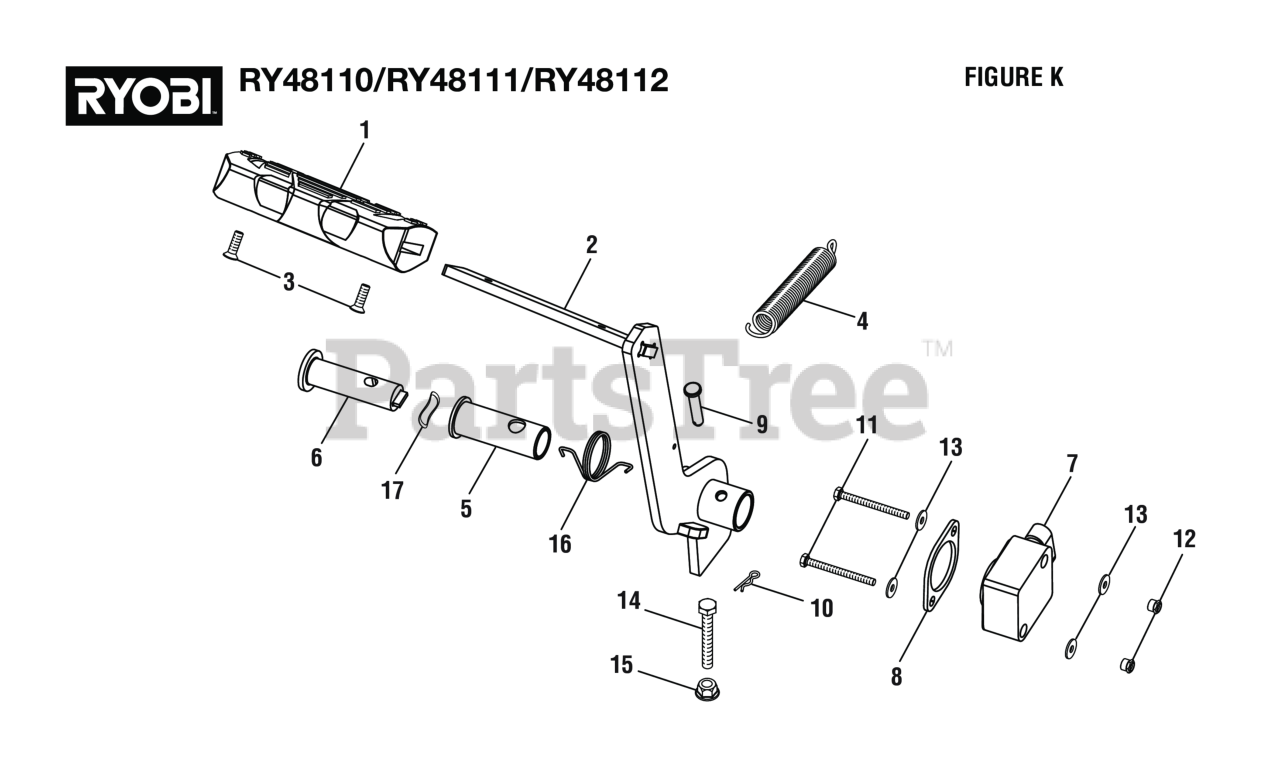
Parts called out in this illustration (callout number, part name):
1	Brake Pedal
2	Acceleration Pedal
3	Screw (M5 x 16 mm, Flat Hd.)
4	Pedal Spring
5	Accelerator Axle Bushing
6	Accelerator Axle
7	Speed Control Switch
8	Control Switch Mounting Bracket
9	Clevis Pin (6 x 30 mm)
10	Cotter Pin (6 mm)
11	Bolt (M4 x 45 mm, Hex Hd.)
12	Nut (M4 x 0.7, Lock)
13	Washer (OD12 x ID4.3 x 1t)
14	Bolt (M6 x 45 mm, Hex Hd.)
15	Flange Nut (M6)
16	Torsion Spring
17	Spring Washer (OD20.5 x ID17 x 0.3t)
